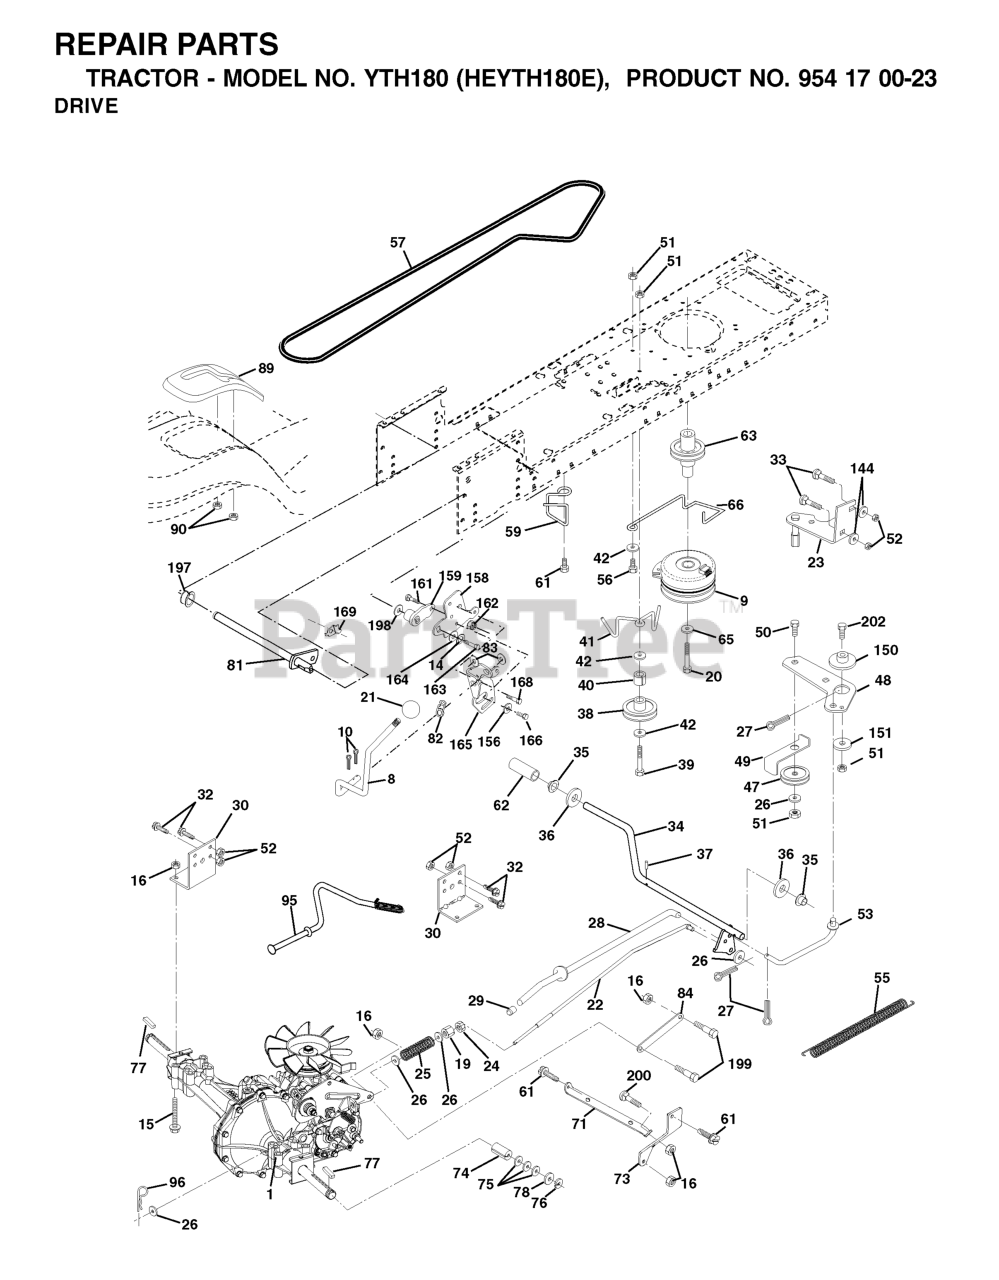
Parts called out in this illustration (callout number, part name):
8	ROD SHIFT FENDER ADJUST STLT
9	ELECTRIC CLUTCH
10	PIN COTTER
14	LOCKWASHER
15	BOLT HEX 5/16-18 GR 5
16	NUT.71038.31-18.HEX.NYLOCK
19	NUT
20	BOLT HEX
21	KNOB.DUCKHEAD.1/2
22	ROD BRAKE HYDRO
24	NUT
25	SPRING ROD LT
26	WASHER
27	COTTER PIN
28	ROD BRAKE PARK LT
29	PLUNGER CAP
30	BRKT, TRNSXLE MNT 20"
32	BOLT
33	RP BOLT 5/16-18 X3/4 ZN/YEL GR
34	SHAFT, FOOT PEDAL
35	BEARING.NYLON
37	DRIVE PIN
38	FLAT IDLER PULLEY
41	KEEPER.BELT.IDLER.FLAT
42	WASHER
47	IDLER PULLEY
48	BELLCRANK, CLUTCH
49	RETAIN BELT
50	BOLT
52	LOCKNUT
53	LINK, CLUTCH LT
55	SPRING, RETURN LT
57	DRIVE BELT, LTH & YTH TRACTORS
59	KEEPER, BELT CENTER
61	SCREW 3/8-16X3/4
62	COVER, PEDAL (1 2)
63	PULLEY, CLUTCH ELECT EVX
65	LOCKWASHER
66	KEEPER BELT ENGINE
71	STRAP TORQUE LH HYDRO
73	STRAP TORQUE RH HYDRO
74	SPACER AXLE
77	SQUARE KEY
81	SHAFT ASM CROSS TAPERED
82	SHIFT SPRING
83	WASHER
84	LINK TRANSAXLE
89	SHIFT CONSOLE
90	NUT.PUSH.3/16
95	CONTROL ASM. BYPASS HYDRO
96	RETAINER M
144	Washer 11/32 x 5/8 x 16 Ga SD
150	BUSHING.BELLCRANK.GRD.DR
151	WASHER 12/32X2X10GA
156	WASHER.SRRTD.5/16
158	BRACKET
159	HUB
161	BOLT
162	NUT.CROWNLOCK.1/4
164	Washer 5/8 x .281 x 10 Ga.
165	RP BRACKET
168	BOLT.SHOULDER.5/16-18X
169	PLATE.FASTENING.CROSS.SHAFT
197	NYLINER SNAP 5/8" ID
198	WASHER.NYL.7/8IDX.105"HYD CR
199	BOLT SHOULDER 5/16-18 UNC
202	BOLT.3/8-16X1.50
